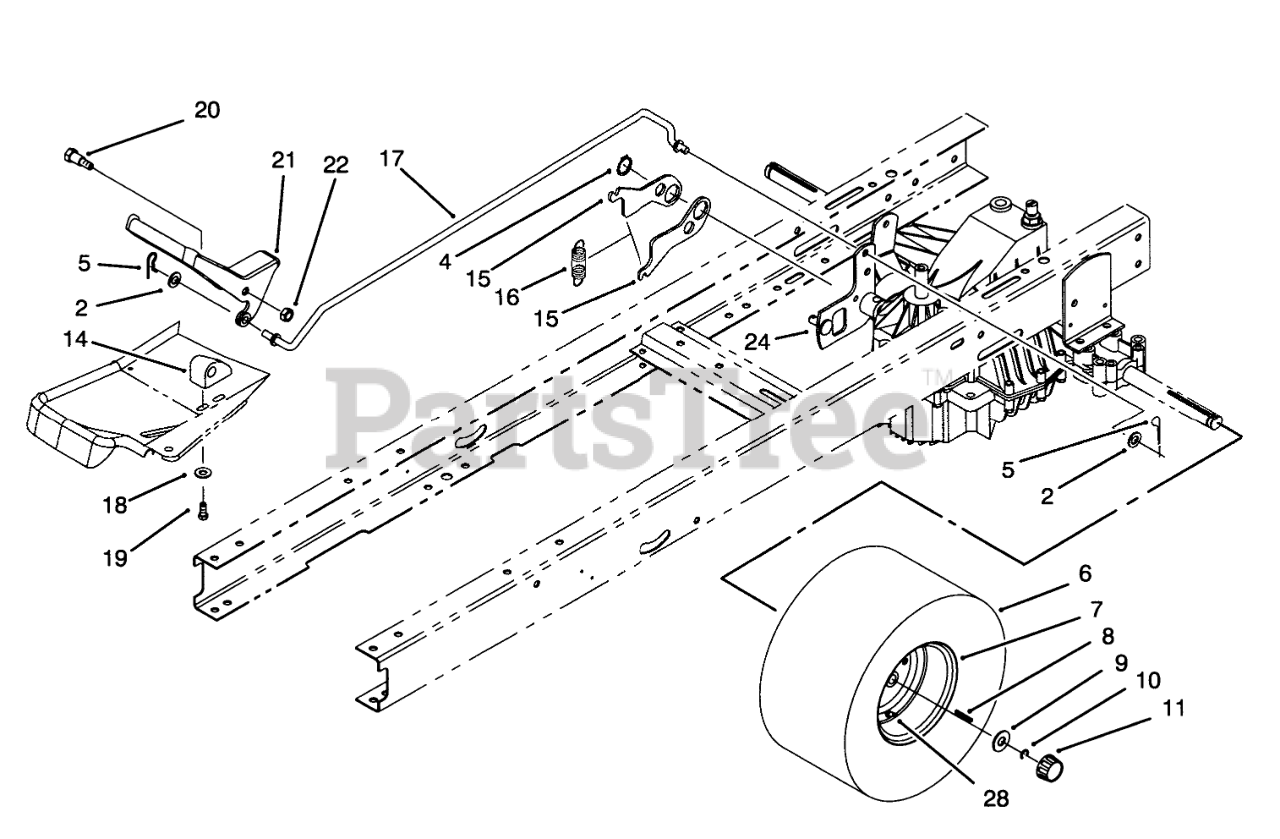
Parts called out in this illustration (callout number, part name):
2	WASHER-PLAIN
4	RING-SNAP
5	PIN-COTTER
6	TIRE 18 X 9.50 X 8
8	KEY-SQUARE
9	WASHER-PLAIN
10	E-RING
11	CAP-HUB
14	BLOCK-PIVOT
15	NEUTRAL RETURN LEVER
16	SPRING-EXTENSION
17	SPEED CONTROL ROD
18	WASHER-FLAT
19	SCREW-PLASTITE
20	SCREW-SHOULDER, HH
21	Pedal-Speed Control
22	NUT-LOCK, NI
28	STEM-VALVE
